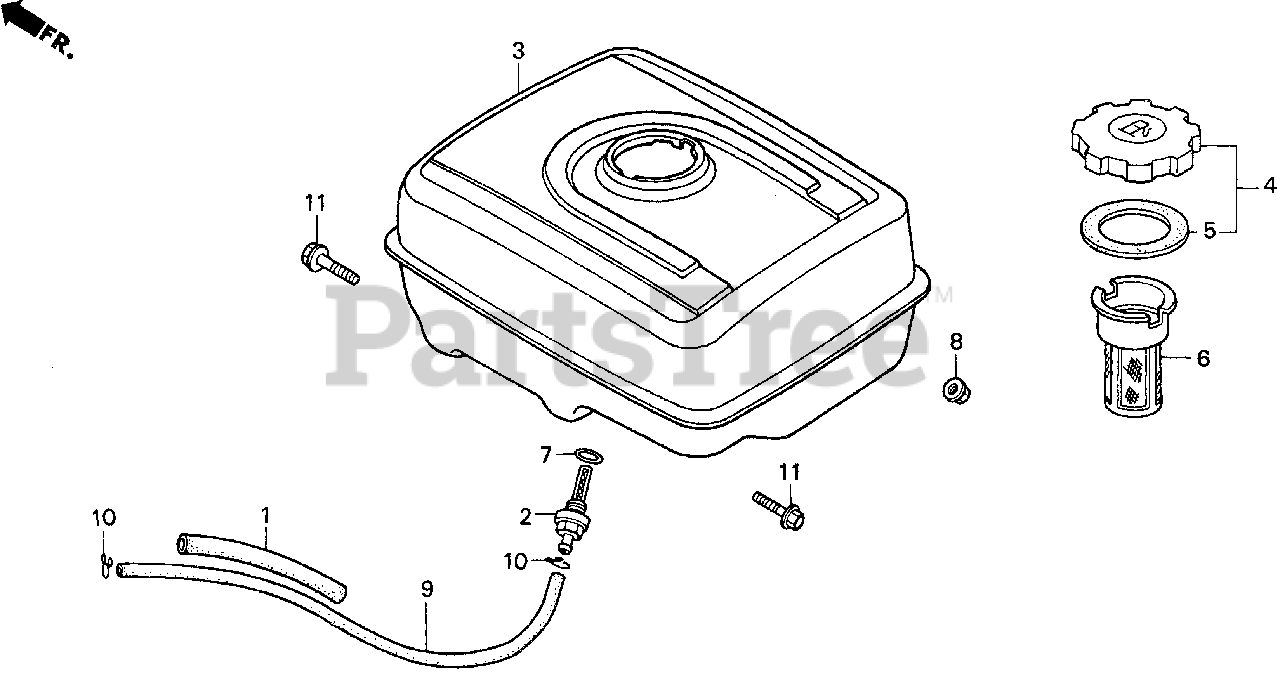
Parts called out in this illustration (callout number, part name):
1	RUBBER, SUPPORTER (107MM)
2	JOINT, FUEL TANK
3	TANK, FUEL *NH1* (BLACK)
4	CAP, FUEL FILLER
5	GASKET, FUEL FILLER CAP
6	FILTER, FUEL
7	O-RING (13.5X1.5) (ARAI)
8	NUT, FLANGE (8MM)
9	BULK HOSE, FUEL (4.5X3000) (4.5X222)
10	CLIP, TUBE (B8)
11	BOLT, FLANGE (8X25)
